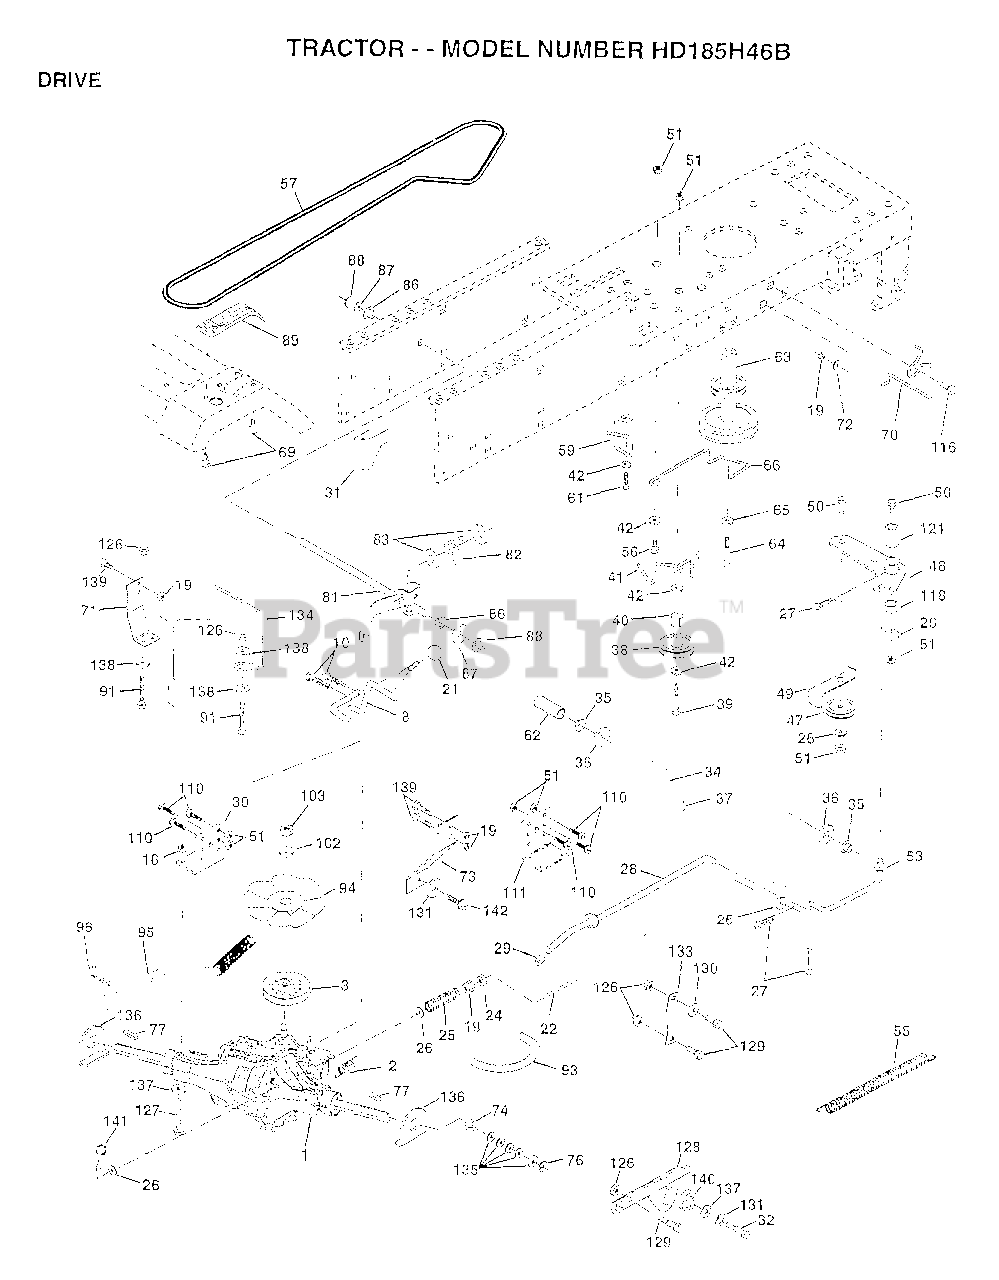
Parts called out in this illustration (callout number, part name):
1	TRANS HYDRO
2	SPRING RET BRAKE
3	PULLEY.TRANSAXLE
6	SCREW
8	ROD SHIFT FEND YT
10	PIN COTTER 1/8
16	NUT
19	NUT
21	KNOB T (1/2-HOLE)
22	BRAKE.ROD.HYDRO.
24	NUT
25	SPRING ROD LT
26	WASHER
27	COTTER PIN
28	ROD.BRAKE.PARK.LT
29	PLUNGER CAP T
30	BRKT TRANS LH
31	KEEPER BELT LH
32	BOLT
34	SHAFT ASM-PEDAL F
35	NYLON BEARING
36	WASHER LT
38	PULLEY.IDLER.FLAT
39	BOLT
40	SPACER T
42	WASHER
48	BELLCRANK ASM
49	RETAIN BELT
53	"LINK, CLUTCH T"
55	"SPRING, RETURN LT"
57	BELT.V.PRI.44.V
59	KEEPER BELT CNTSP
61	SCREW
62	PEDAL COVER T
63	PULLEY.ENGINE
64	BOLT
65	LOCKWASHER
66	KEEPER-BELT
69	SCREW HEXWSH H-L
70	"GUIDE.BELT,RH ENG"
71	STRAP.TORQUE.LH.HYDRO
72	WASHER
73	STRAP.TORQUE.RH.HYDRO
76	E RING HYT
77	SQ KEY STD
81	SHAFT ASM. CROSS HYDRO 20" TIRES
82	"SPRING,TORSION"
83	WASHER
86	BUSHING
87	WASHER D
88	KLIP RING
93	"LINE FUEL HYD 4"""
94	"FAN 7"" HYDRO"
95	CONTROL.ASM.BYPAS
96	RETAINER M
100	WASHER M
102	WASHER BELLEVILLE
111	BRKT TRANS RH
116	BOLT RDHD 3/8-16
118	SPACER-BELLCRANK
121	NYLINER-CLUTCHING
127	BOLT FIN HEX 5/16
128	BRKT NEUTRAL ADJ
130	WASHER
132	WASHER
133	LINK.SHIFT-HYDRO
134	"KEEPER BELT,RH"
135	WASHER
136	WASHER AXLE HYDRO
137	WASHER
138	WASHER
139	BOLT
140	BUSHING.PINION.SECTOR
142	BOLT.5/16X24X1
